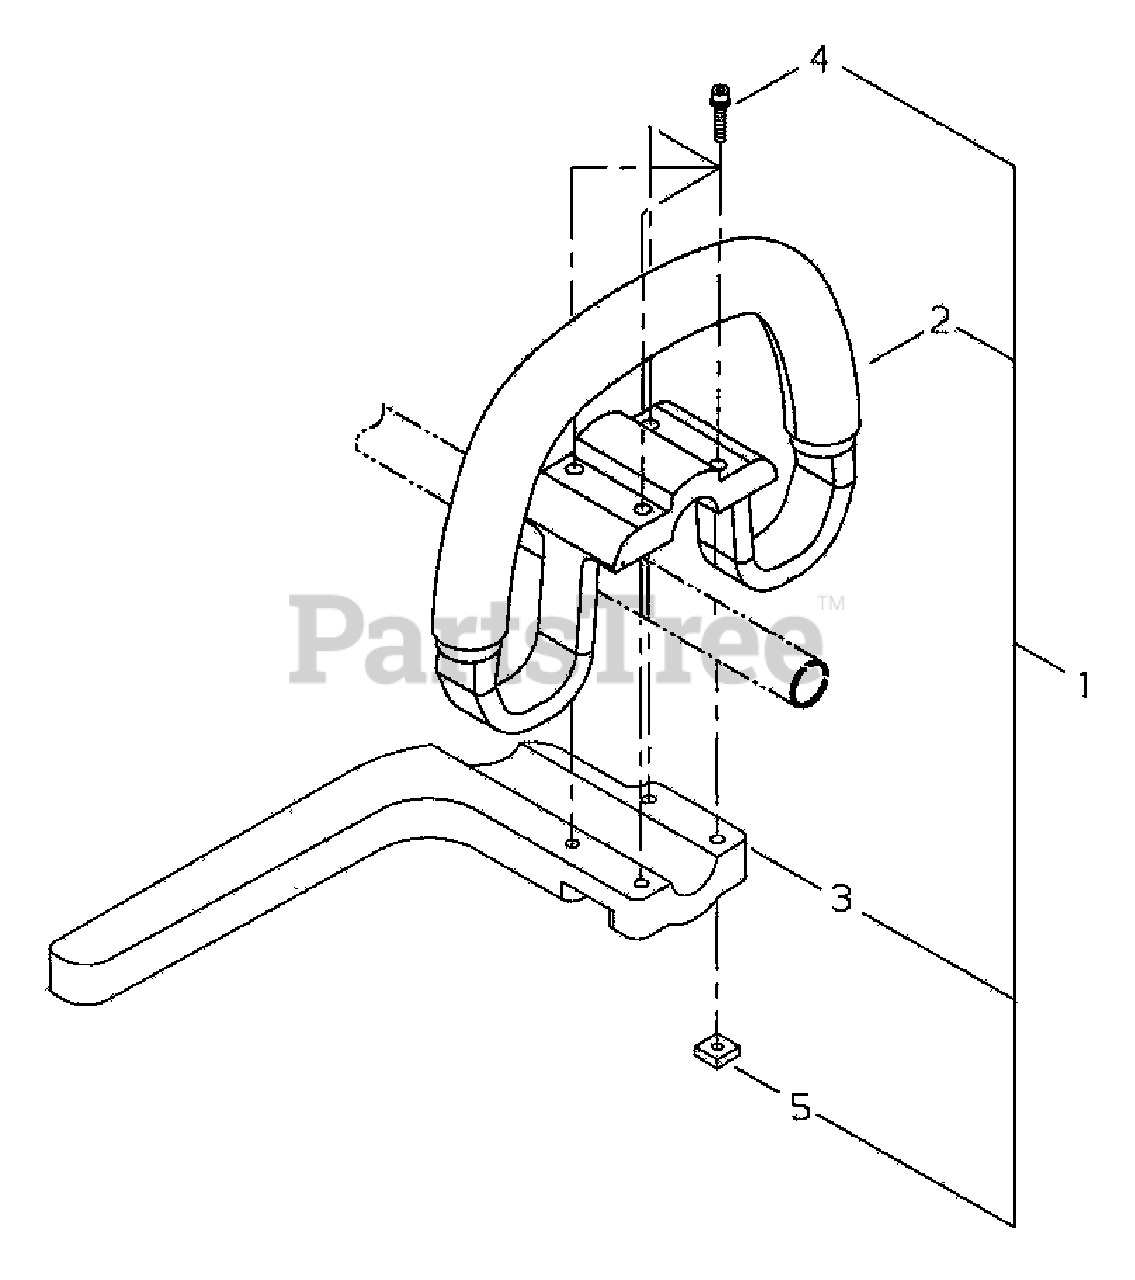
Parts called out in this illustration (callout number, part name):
1	HANDLE ASSY
2	HANDLE, SUPPORT
3	BAR, BARRIER
4	BOLT M5×35
5	NUT M5
